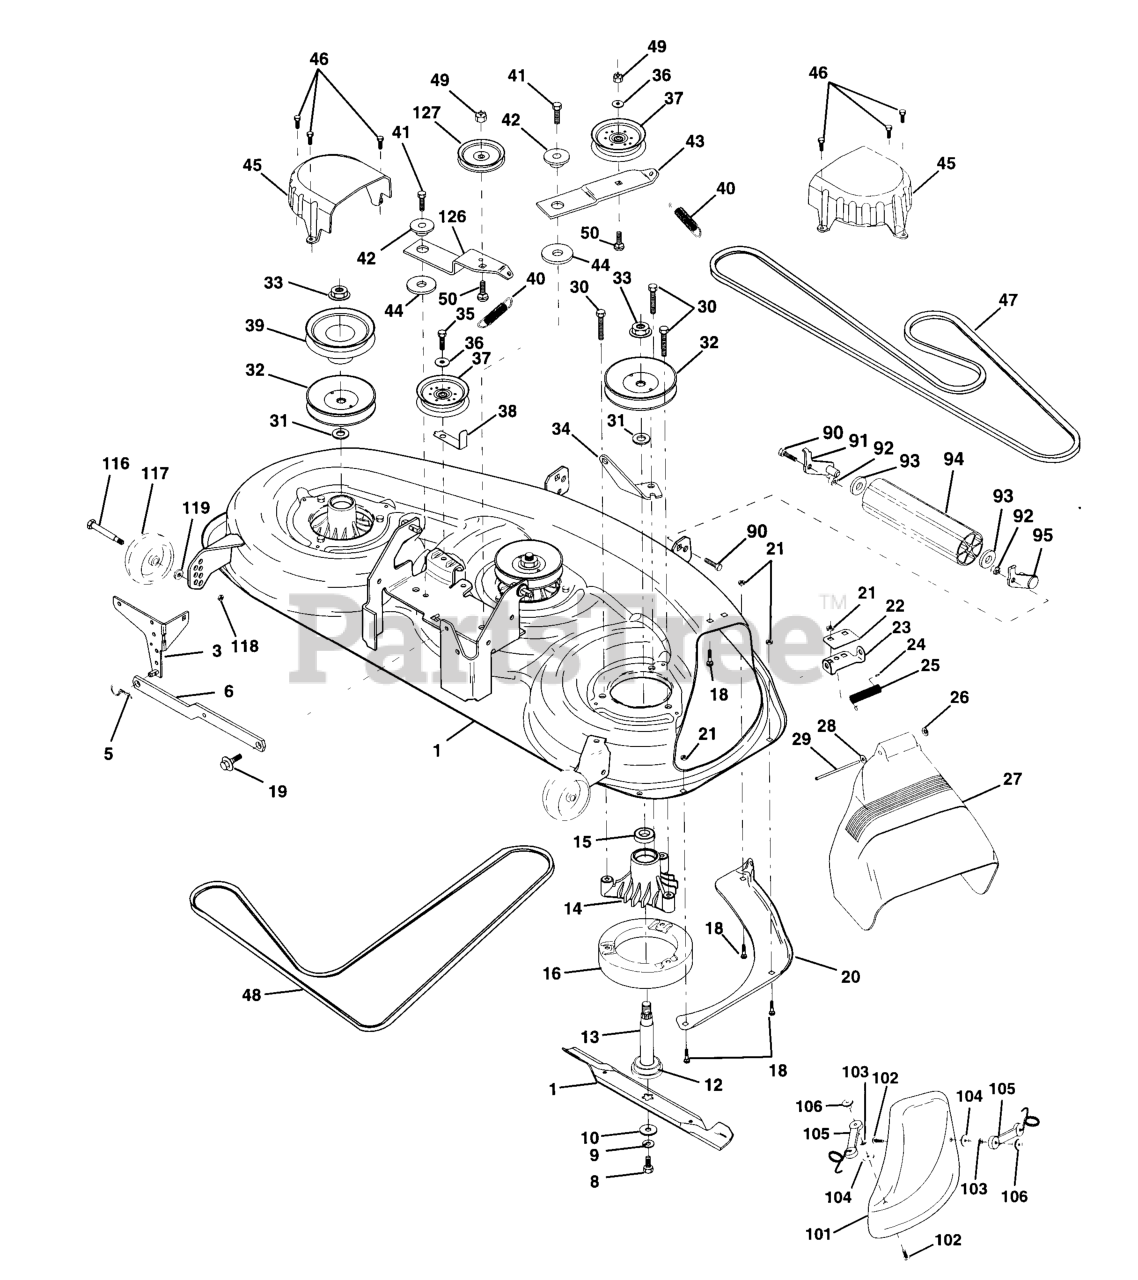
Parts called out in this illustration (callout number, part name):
1	DECK ASM, MOWER 46"
3	BRACKET SWAY BAR
5	RETAINER-SPRNG RB
6	REAR SUSP ARM
8	BLADE BOLT
9	LOCKWASHER
10	WASHER.BLADE
11	BLADE MULCH 46"
12	BEARING.BALL.#6204.(MANDREL)
13	SHAFT.ASM.W/BEARING
14	HOUSING.MANDREL.44/46" VENT
16	STRIPPER
18	BOLT
19	BOLT SHD 5/16-18
20	BAFFLE, VORTEX MOWER 46"
21	LOCKNUT
22	STIFFENER BRACKET
23	DEFLECTOR BRACKET
24	CAP-SLEEVE LT
25	TORSION SPRING
26	NUT PUSH M
27	SHIELD, DEFLECTOR MOWER
28	Washer 11/32 x 5/8 x 16 Ga.
29	ROD.HINGE
30	SCREW
31	WASHER
32	PULLEY
33	NUT
34	ANCHOR, SPRING DECK 46"
35	SCREW LT
36	WASHER
37	FLAT IDLER PULLEY
38	KEEPER
39	PULLEY.DRIVEN.DECK.46"
40	SPRING.SEC.44"VEN
41	SCREW
42	SPACER RETAINER
43	ARM IDLER DECK 46"
44	HARDENED WASHER
45	COVER MANDREL 46
46	SCREW.1/4-20X5/8
47	BELT V SECONDARY
48	V-BELT PRIMARY 50"
50	BOLT.3/8-16X1.50
90	BOLT
91	BRACKET LH (A)
92	NUT
93	Washer 17/32 x 7/8 x 16 Ga.
94	NOSE ROLLER
95	BRACKET RH (B)
101	COVER.MULCH.46"3-BLADE.(2 2)
102	SCREW
103	LOCKWASHER #10
105	LATCH ASSEMBLY
106	WELDNUT
116	BOLT, SHOULDER
117	WHEEL GAGE DONUT
118	LOCKNUT
119	WASHER.5/16.FLAT.STE.STD.
126	ARM IDLER PRIM 46
127	PULLEY.IDLER.4.25
128	SHIELD IDLER
